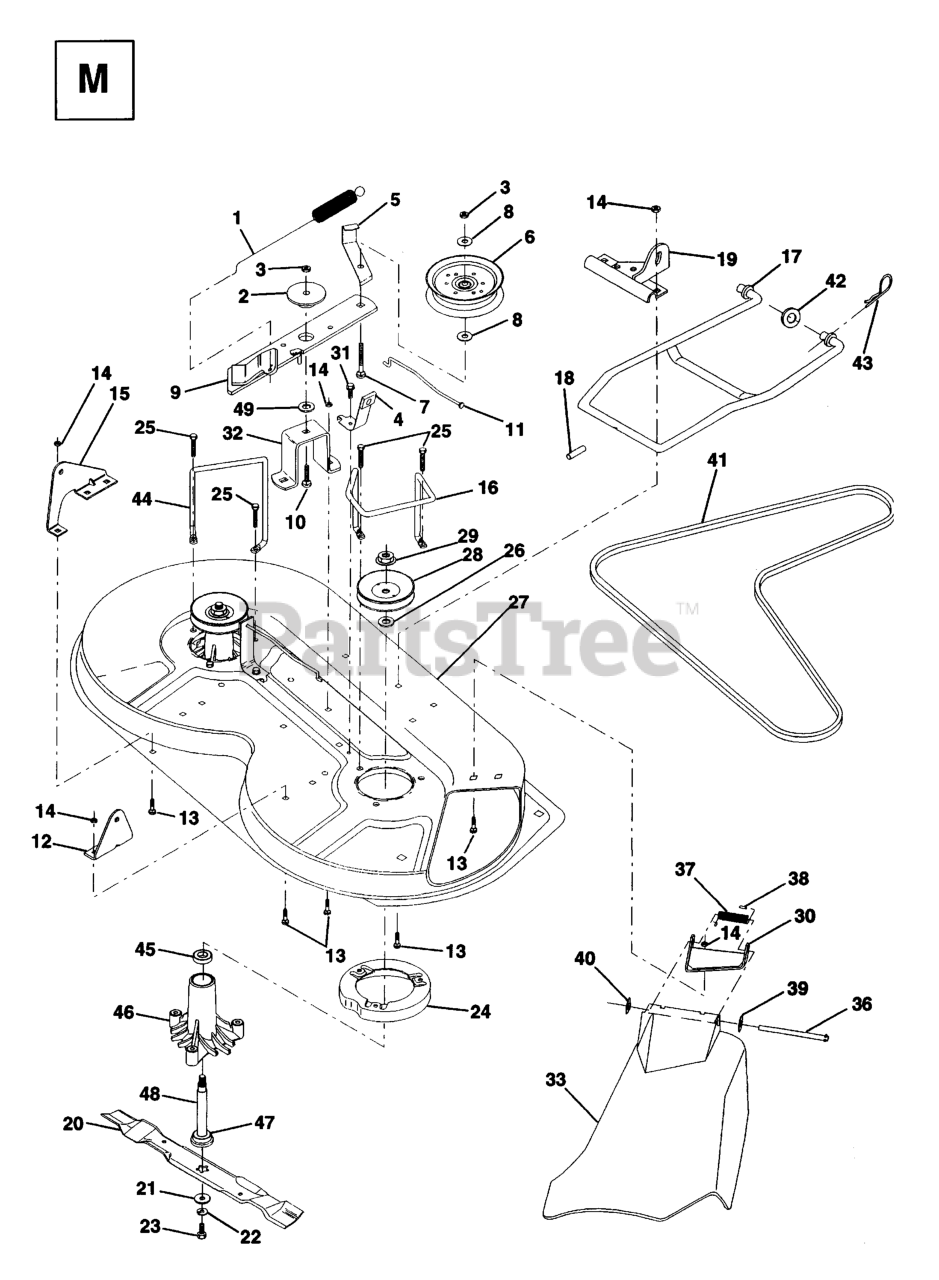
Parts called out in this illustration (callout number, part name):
1	SPRING-MOWER CLUTCH
2	SPACER RETAINER
3	NUT
4	BRAKE ASSEMBLY
5	IDLER BELT GUIDE
6	PULLEY.IDLER.FLAT.MOWER.BLK.PT
8	WASHER
9	IDLER ARM ASSY
10	BOLT D
12	BRKT LIFT REAR
13	BOLT
14	LOCKNUT
15	BRKT LIFT REAR LH
16	KEEPER RH
17	MOWER LINK STABILIZER
18	PIN GROOVE
19	BRKT LINK STABILIIZER
20	BLADE
20	BLADE.36".MULCH
21	WASHER.BLADE
22	LOCKWASHER
23	BLADE BOLT
24	STRIPPER
26	WASHER
27	MOWER HOUSING
28	PULLEY
29	NUT FLANGELOCK 9/16
30	BRACKET ASM DEFLECTOR
31	Screw 5/16-18 x 1/2 Hex, Self Tapping 5/16-18 x 1/2
32	SUPT,IDLER ARM
33	DEFLECTOR
36	HINGE ROD
37	SPRING TORSION
38	CAP-SLEEVE LT
39	Washer 11/32 x 5/8 x 16 Ga SD
40	NUT PUSH M
42	WASHER
43	SPRING RETAINER
46	HOUSING.MANDREL.VENTED (MACHD)
47	BEARING.BALL.#6204.(MANDREL)
48	SHAFT ASM VENT
49	HARDENED WASHER
